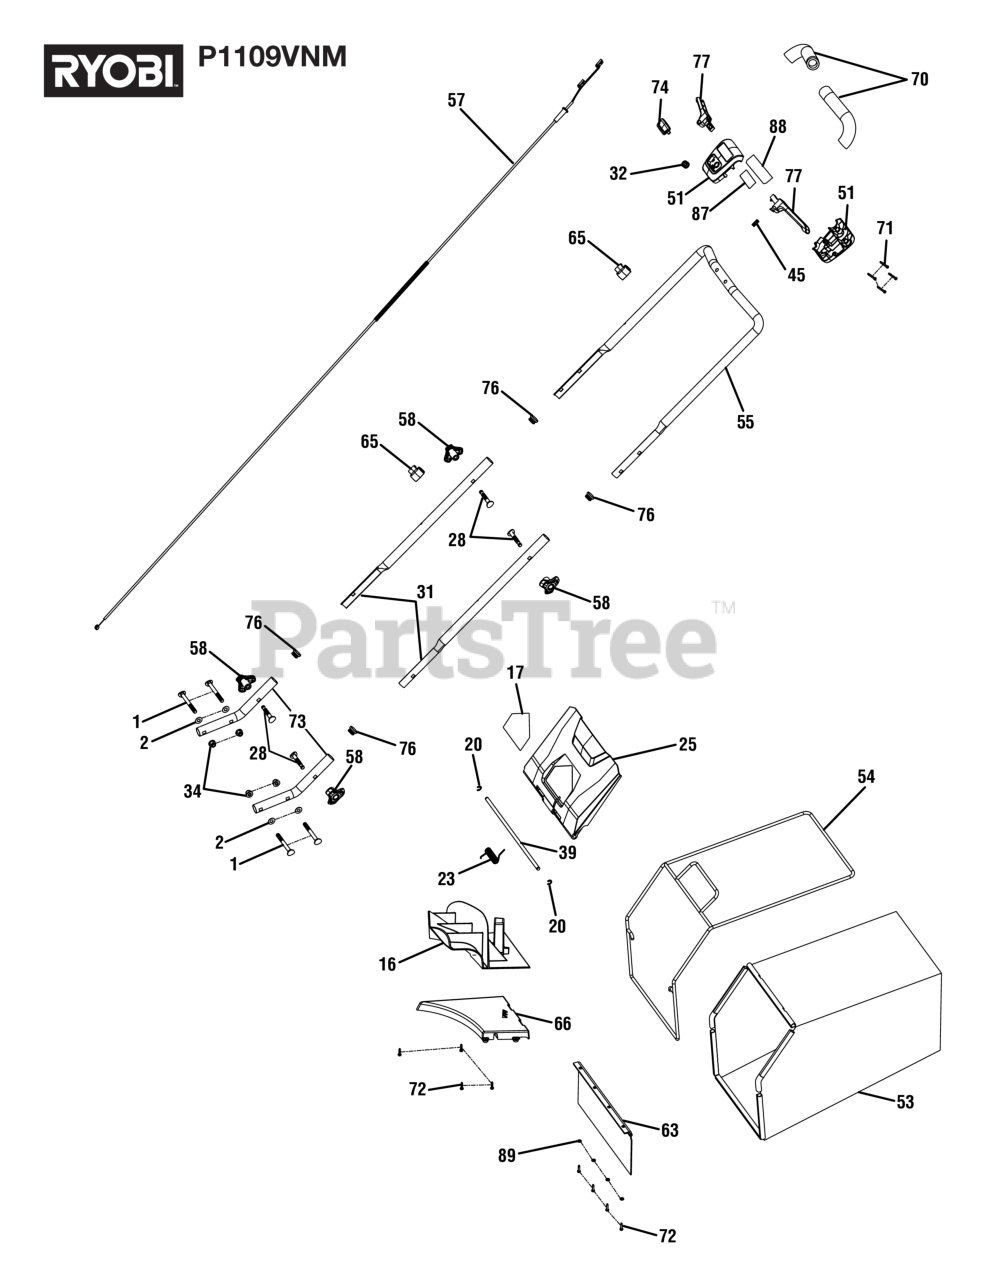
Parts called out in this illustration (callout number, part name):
1	Screw (M8 x 80 mm, Hex. Recess Hd.)
2	Washer (ID8.4 x OD18 x 1t)
16	Mulching Plug
17	Danger Label (No Hands/Feet)
20	Retaining Ring (E)
23	Torsion Spring (Rear Door)
25	Rear Door Assembly (Inc. Key No. 17)
28	Screw w/Square Shoulder (M8 x 57 mm)
31	Lower Handle Tube
34	Flange Lock Nut (M8 x 1.25 mm)
39	Rear Door Axle
45	Compression Spring (Trigger)
51	Switch Box Assembly (Inc. Key Nos. 87-88)
53	Grass Bag
54	Grass Bag Frame
55	Upper Handle Tube
57	Inner Wire and Plug Assembly
58	Wing Nut w/Insert (M8)
63	Trailing Shield Guard
65	Cable Clip
66	Rear Discharge Baffle
70	Foam Tube
71	Screw (M4-18 x 30 mm, T15 Torx Soc. Hd.)
72	Screw (M4 x 18 mm, T20 Torx Pan Hd.)
73	Deck Tube
74	Safety Button
76	Steel Tube End Plug
77	Trigger Assembly
87	Logo Label
88	Instruction/Logo Label
89	Washer (ID4.5 x OD10 x 1t)
